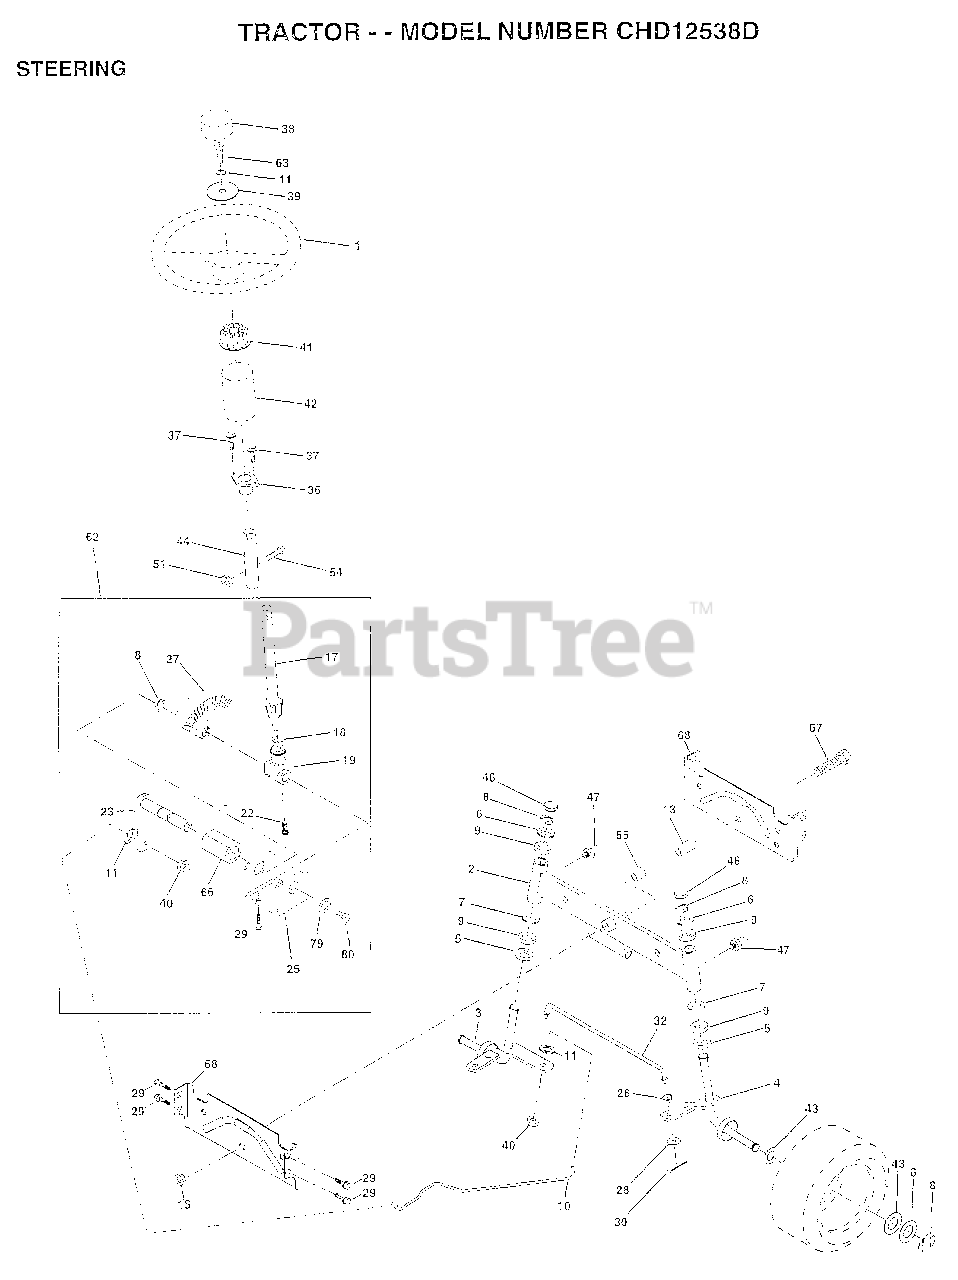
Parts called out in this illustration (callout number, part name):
1	WHEEL STR AYP BLK
2	AXLE ASM
3	SPINDLE.ASM.LH
4	"SPINDLE ASM,RH"
5	WASHER .T
6	WASHER
7	WASHER
8	RING
9	COL. SRTG. BEAR.
10	DRAGLINK-STAMPED
11	LOCKWASHER
13	BEARING AXLE
15	"NUT-LOC,FLANGE LT"
17	SHAFT ASM STEERIN
18	THRUST WASHER
19	SUPPORT.SHAFT.STEER
22	SCREW.HX.WSH.HD
23	SHAFT.ASM.PITMAN
25	BRKT-STEERING
26	BUSHING.DRAGLINK
27	GEAR SECTOR
28	WASHER
29	SCREW
30	COTTER PIN
32	TIE ROD
36	BUSHING.STEERING
37	"SCREW-TT,10-32 FL"
38	CAP STEER AYP
39	WASHER T
40	GRIPCO NUT
41	ADAPTER LT
42	BOOT.STEER.PL
43	WASHER
44	EXT SHAFT STEERIN
46	CAP
47	ZERK M
51	NUT
54	BOLT
62	KIT.STEER.ASM
63	BOLT
65	SPACER AXLE
66	"BEARING-ARM,PITMA"
67	BOLT
68	BRACE AXLE
79	WASHER
80	BOLT.HX.NYLON3/8-16X3/
